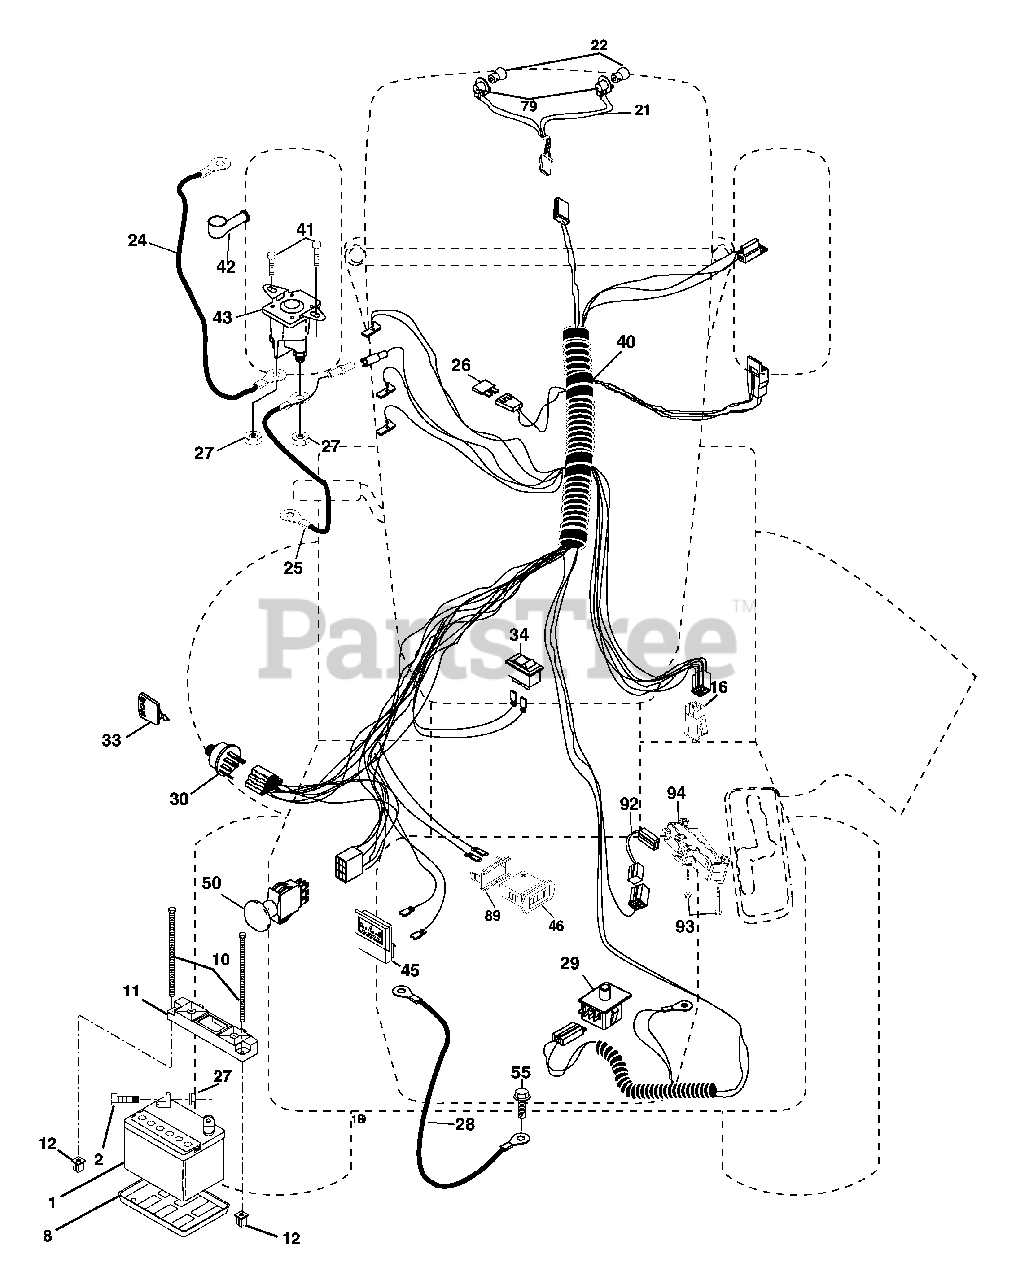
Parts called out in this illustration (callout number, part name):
1	Battery
2	Bolt Hex Hd 1/4-20 unc x 3/4
8	Tray, Battery
10	Bolt, BTR FRT 1/4-20 x 7.5
11	Hold Down Battery, Front
12	Nut, Push, Nylon
16	Switch Interlock Push-In
21	Harness Asm Light W/Bulbs
22	Bulb Light
24	Cable Starter
25	Cable
26	Fuse
27	Nut Keps Hex 1/4-20 unc
28	Cable Ground
29	Switch Seat
30	Switch Ign
33	Key Ign
34	Switch Light/Reset
40	Harness Ign.
41	Key
42	Cover Terminal
43	Solenoid w/Brass Plunger
45	Ammeter
46	Hourmeter Snap-In
50	Switch, PTO
55	Screw Thdrol 5/16-18 x 1/2
79	Bulbholder
89	Bracket Snap-In Hourmeter
92	Harness Pigtail Reverse Switch
93	Screw Plastite 10-1/4 x 2.0
94	Module Reverse Switch
